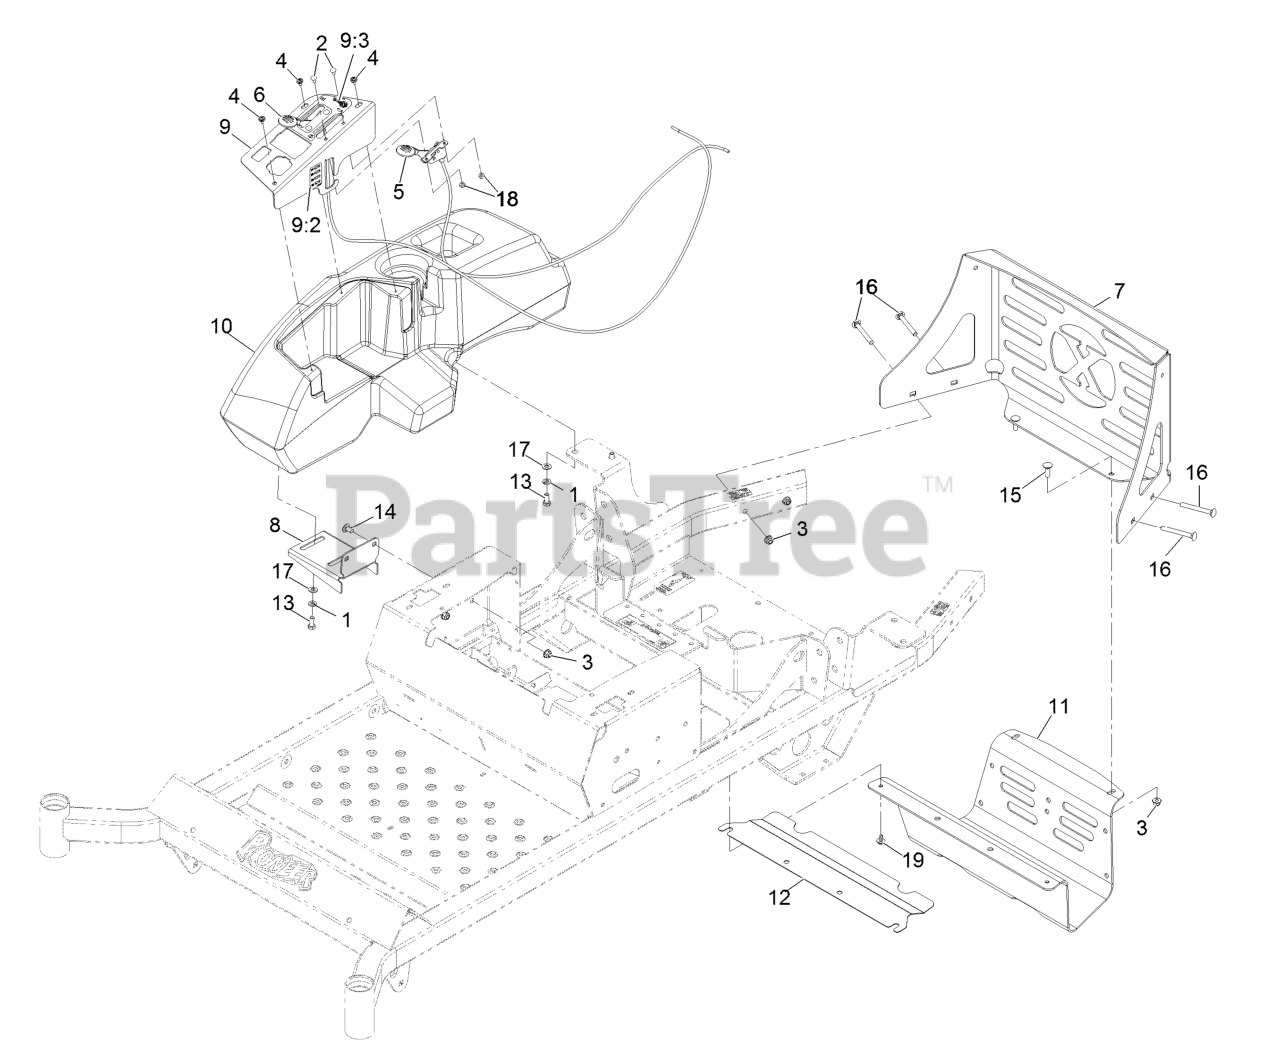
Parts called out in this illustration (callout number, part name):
1	WASHER-LOCK
2	BOLT-CARR
3	NUT-HF, NI
4	SCREW-PPH
5	CONTROL,THROTTLE
6	CONTROL,CHOKE
7	PANEL,REAR GUARD
8	BRACKET-TANK AND FENDER
9	ASM,CONTROL PANEL W/DECAL
9:2	DECAL,FUSE BLOCK
9:3	DECAL-THROTTLE CHOKE
10	CONSOLE,RH
11	GUARD-MUFFLER
12	SHIELD, HEAT
13	SCREW-HH
14	SCREW-CARR
15	BOLT-CARR
16	SCREW-CARR
17	WASHER-PLAIN
18	NUT-LOCK, NI
19	SCREW-HHFTF
